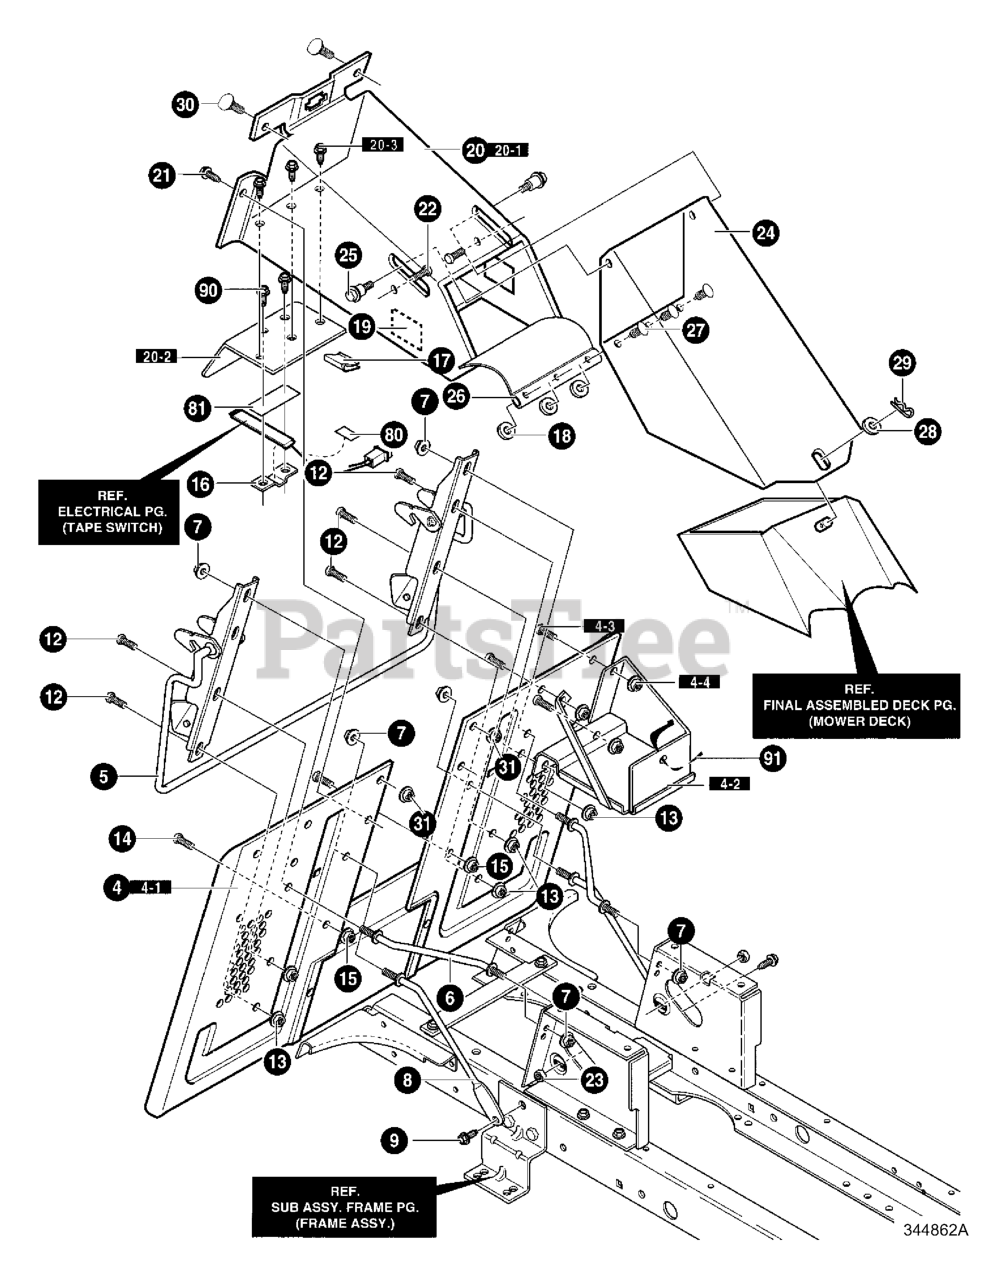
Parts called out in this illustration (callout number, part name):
4	ASSY, BACK PLATE/BATTERY
4-1	ASM. BACKPLATE FLAT
4-2	BATTERY TRAY ASM.
4-3	SCREW, 5/16-18 x 0.50 HHC
4-4	NUT, 5/16-18 HEXWDFLLK WHIZ
5	WELDMENT - LATCH LEVER
6	ROD, BRACE
7	NUT, 3/8-16 HWDFL WHIZ-LOCK
8	ROD, BRACE
9	SCREW, 5/16-18 x 0.75 HHWATAP
12	SCREW 5/16-18X.75 WDFLW
13	NUT, 5/16-18 HEXWDFLLK WHIZ
14	SCREW 5/16-18X.75 HHWATAP
15	NUT, 5/16-18 HEXWDFLLK WHIZ
16	BRACKET, FLEX SWITCH MOUNTING
17	WIRE CLIP, ADHESIVE
18	FLATWASHER, .250X.56X.047
19	PAD, ADHESIVE 1.00X1.50X.12
20	ASM., T/A SHIELD & UPPER CHUTE
20-1	CHUTE WELD ASM. UPPER
20-2	SHIELD, TRANSAXLE
20-3	SCREW, 1/4-20X.63 HHWATAP
21	SCREW, 5/16-18 x.75 HHC
22	BOLT, 5/16-18X.75 CARR
23	NUT, 5/16-18 HEXWDFLLK WHIZ
24	MIDDLE CHUTE ASSY
25	BOLT, SHOULDER, 3/8-16
26	FLAP, CHUTE
27	FASTENER, RATCHET
28	FLATWASHER
29	PIN, HAIR .38DIAX1.64LG
30	BOLT, 5/16-18X.75 CARR.
31	NUT, 5/16-18 HEXWDFLLK WHIZ
80	TAPE, DOUBLE SIDED FOAM 3/4" WD
81	TAPE, DOUBLE SIDED FOAM 3/4" WD
90	SCREW, 1/4-20X.63 HHWATAP
91	CABLE TIE
